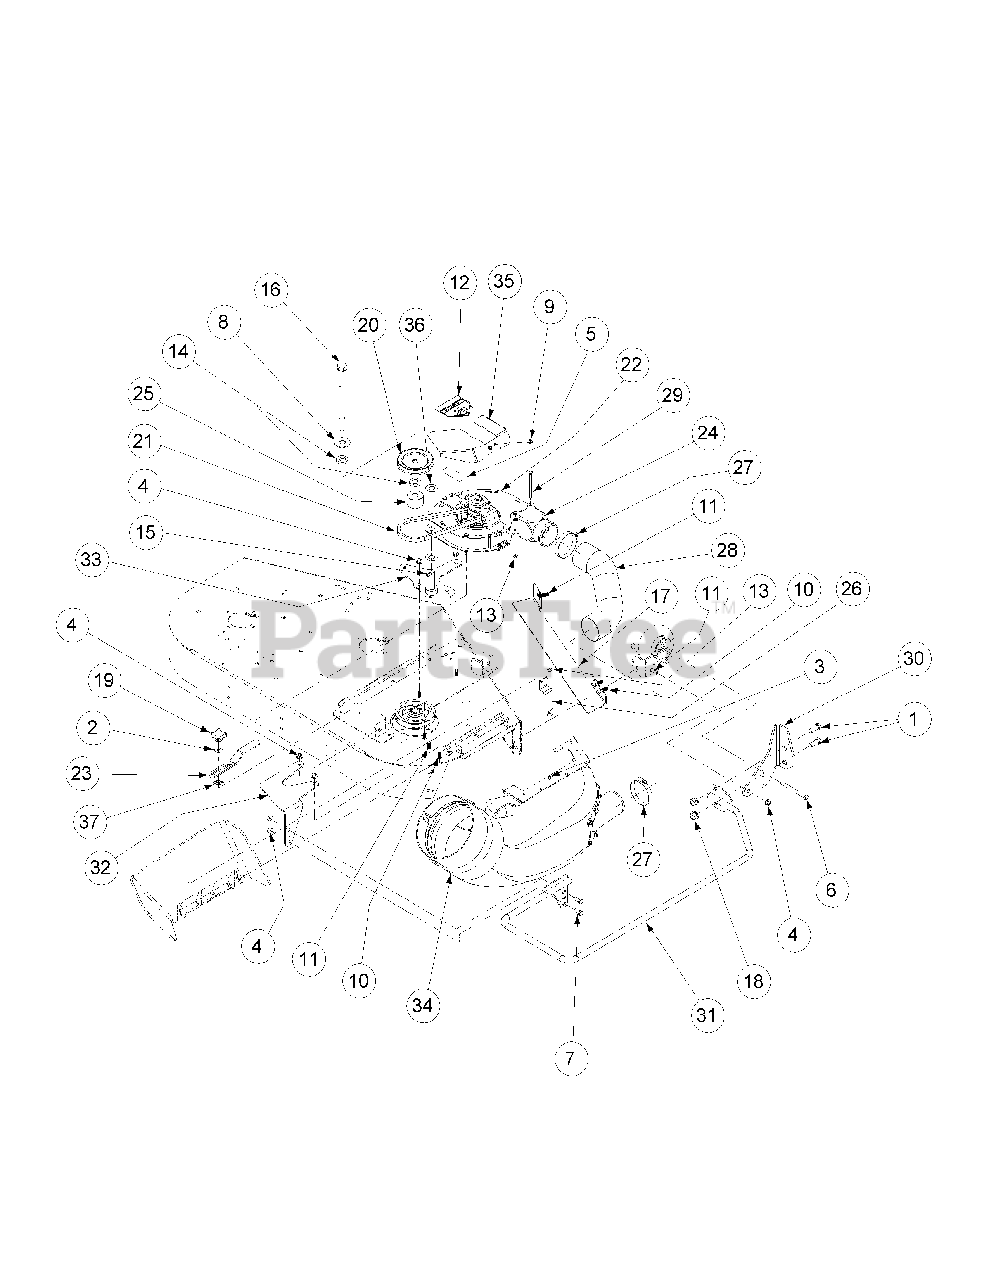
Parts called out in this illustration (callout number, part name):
1	HHCS, 1/2-13 x 1.25
2	Flat Washer, 3/8
3	Hex Cap Screw, 1/4-20, .75
4	Hex Nut Flange Lock, 3/8-16
5	Decal, Warning Shield Missing
6	HHCS, 3/8-16 x 4.50
7	HHCS, 3/8-16 x .88
8	Flat Washer, .781 ID x 2.00 OD x .105
9	Screw, TT, 1/4-20, 0.5, Hex Index Washer
10	Carriage Bolt, 3/8-16 x 1
11	Carriage Screw, 3/8-16 x 1.25
12	Decal, Danger Hands & Feet
13	Lock Nut, 1/4-20
14	Spacer, .812 ID x .268 Lg.
15	Cotter Pin, .148 x 3.00
16	Hex Cap Screw, 3/4-16, 8.50
17	Baffle Bracket
18	Nut, 1/2-13, Flange Lock
19	Plastic Knob
20	Pulley, V-Type .4.5 Dia.
22	Blower Assembly
23	Tension Assembly
24	Adaptor Tube
25	Spacer, .76 OD x 2.00 OD x 1.28
26	Chute Stop Deflector Bracket
27	Hose Clamp, 3.00 Dia.
28	Hose Duct
29	HHCS, 1/4-20 x 3.50
30	MCS Guard Plate
31	MCS Guard Weldment
32	MCS Guard Support Plate
33	Pivot Weldment
34	Chute Elbow Assembly
35	Deck Blower Deflector Cover
36	Flat Washer, .76 x 1.49 x .06
37	Push Retainer
